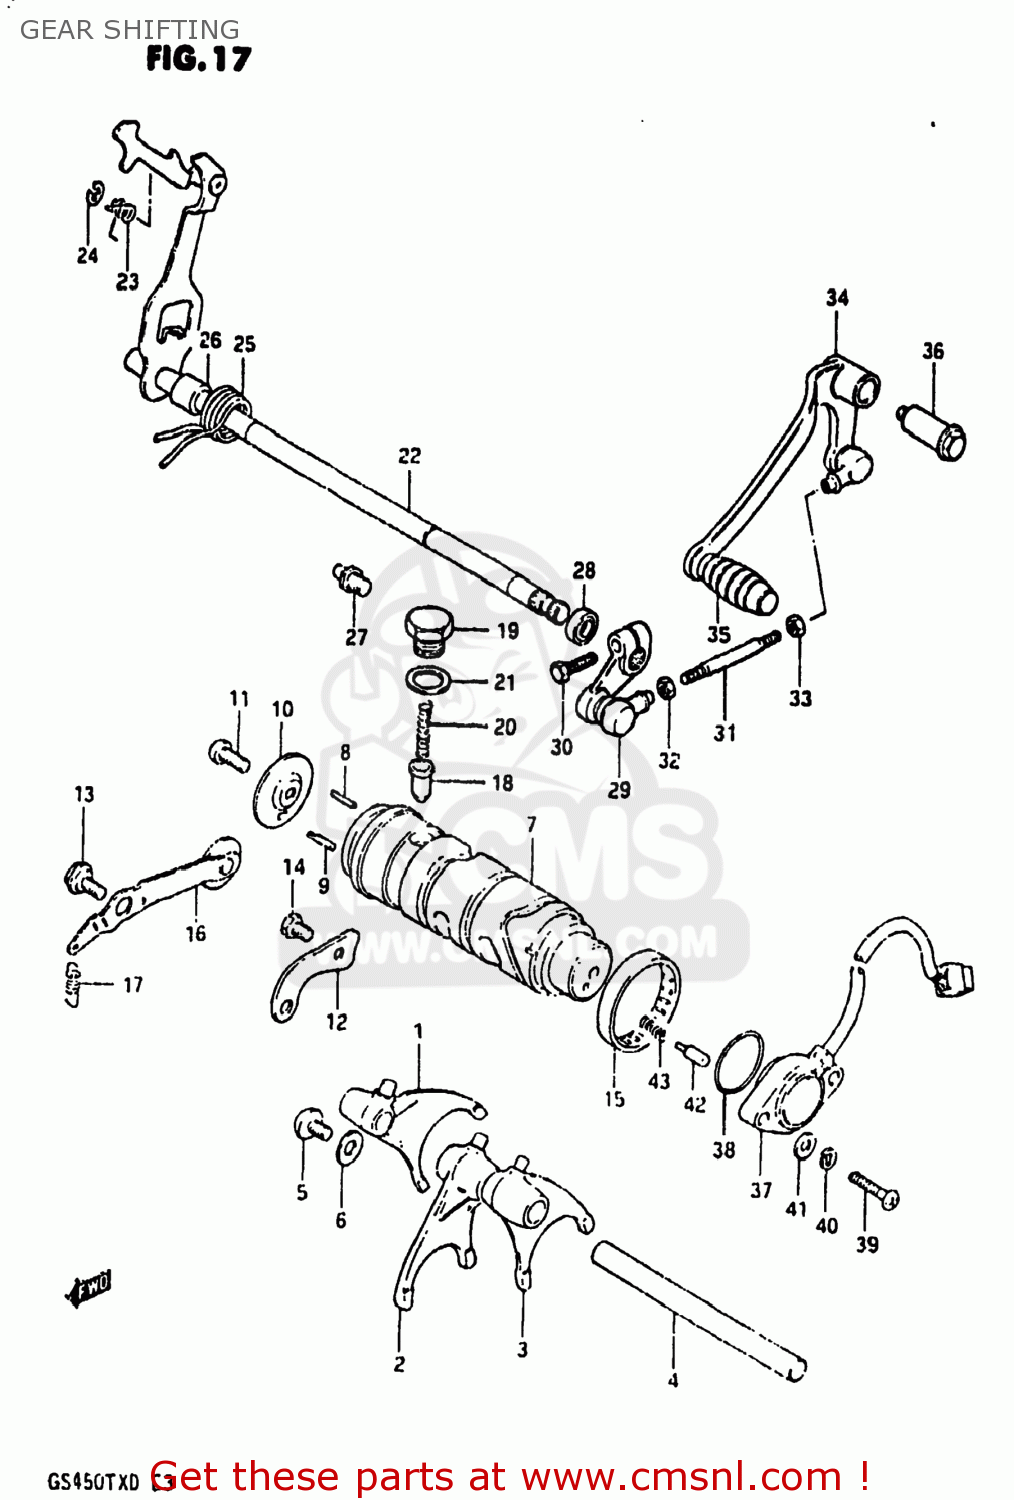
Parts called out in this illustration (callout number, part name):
1	FORK,GEAR SHIFT NO.1
2	FORK,GEAR SHIFT NO.2
3	FORK,GEAR SHIFT NO.2
4	SHAFT,GEAR SHIFT FORK
5	SCREW
6	WASHER
7	CAM,GEAR SHIFT
8	PIN(4X18.5)
9	PIN
10	RETAINER,GEAR SHIFT CAM DR PIN
11	SCREW
12	GUIDE,GEAR SHIFTING CABLE
13	BOLT
14	BOLT, UPPER
15	BEARING(40X47X12)
16	STOPPER,GEAR SHIFT CAM NO.1
17	SPRING
18	STOPPER,GEAR SHIFT CAM NO.2
19	HOLDER,GEAR SHIFT CAM STOP SPR
20	SPRING
21	GASKET(14X19.2X2) (NAS)
22	SHAFT,GEAR SHIFT
23	SPRING
24	E RING
25	SPRING
26	SPACER(12X20X15.3)
27	STOPPER,GEAR SHIFT CAM
28	OIL SEAL
29	ARM,GEAR SHIFT LINK
30	BOLT
31	ROD,GEAR SHIFT LINK
32	NUT
33	NUT
34	LEVER ASSY,GEAR SHIFT
35	RUBBER,GEAR SHIFT PEDAL
36	SHAFT,GEAR SHIFT LEVER
37	BASE ASSEMBLY,NEUTRAL SWITCH TERMINAL
38	O-RING (D:2.4 ID:26.2)
39	SCREW 5X20
40	LOCK WASHER
41	WASHER
42	PIN(5X15.5)
43	SPRING
